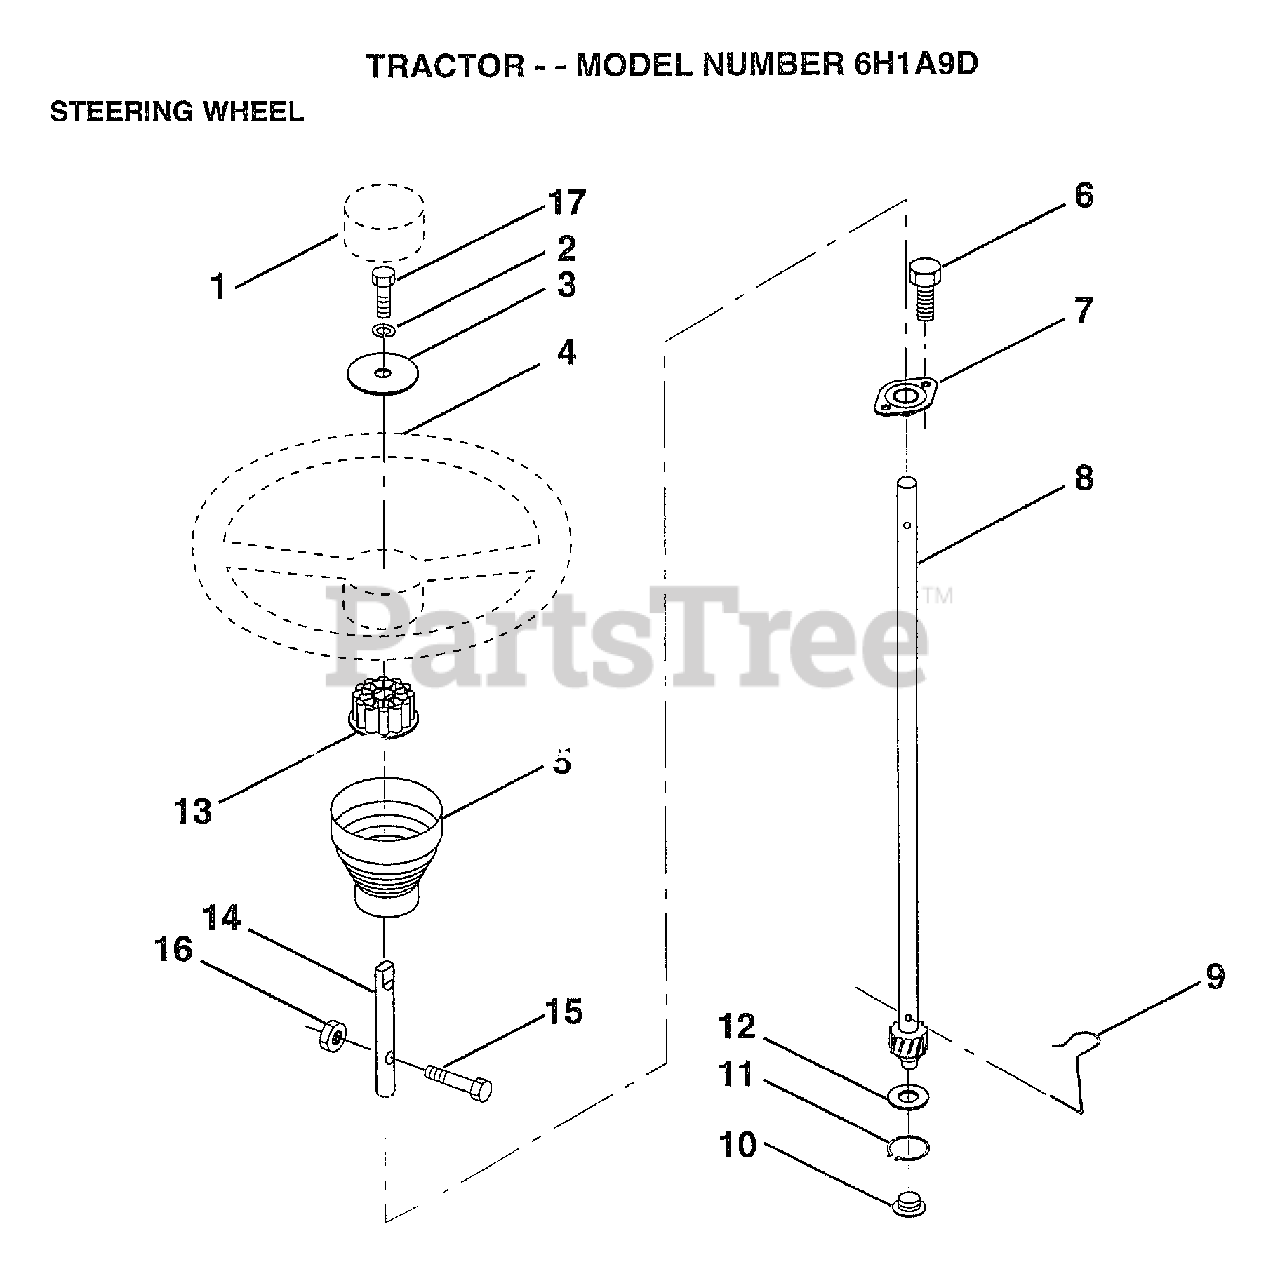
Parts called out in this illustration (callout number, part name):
1	ST WHL INSERT CAP
2	LOCKWASHER
3	WASHER T
5	SLEEVE STEERING
8	SHAFT.STEERING.LR
9	STEERING CLIP
10	BUSHING STEER LWR
11	RING
12	WASHER LT
13	ADAPTER LT
14	EXTENSION SHAFT STER.
15	BOLT, 5/16-18 X 1-1/4
16	NUT
